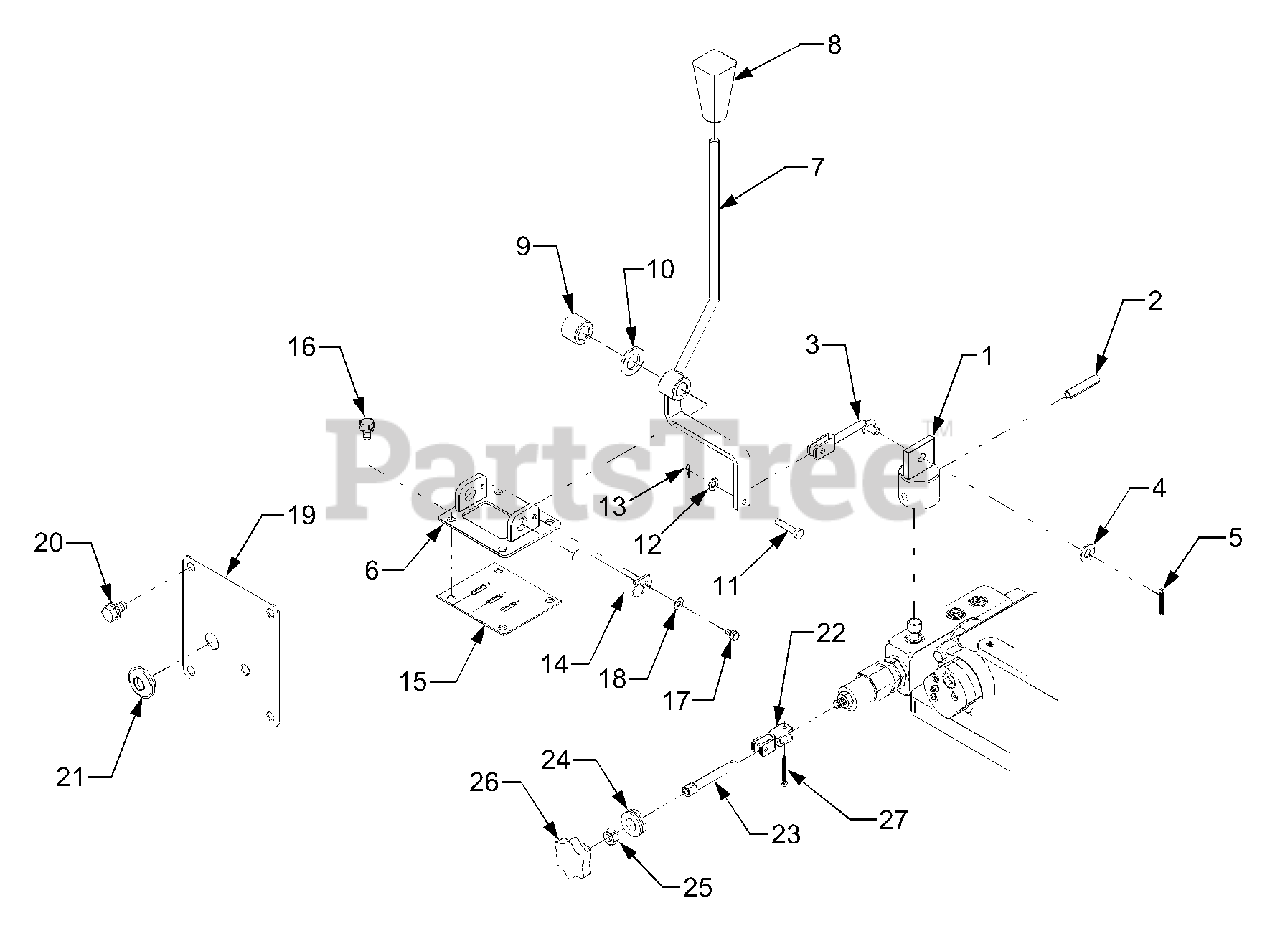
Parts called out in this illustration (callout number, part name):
1	Lever 1, Double Acting
4	Washer, Plain
12	Washer, Plain
18	Washer, Plain
19	Plate (Bracket)
